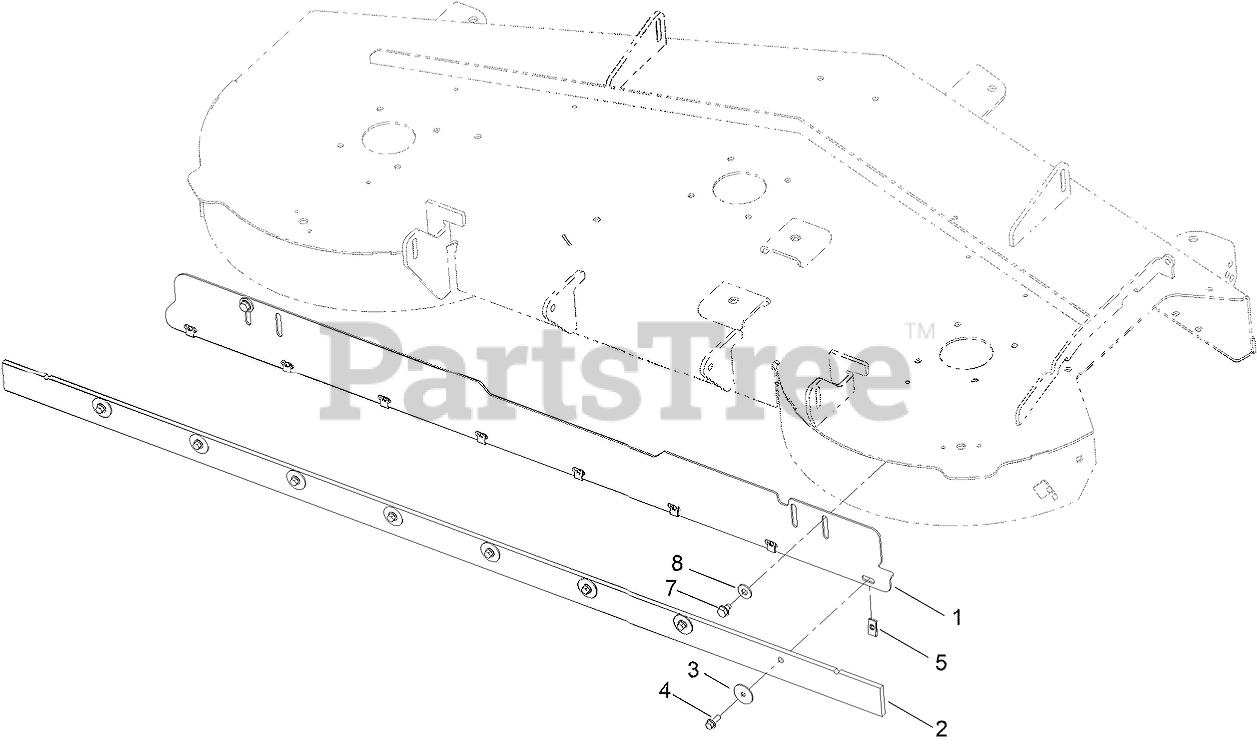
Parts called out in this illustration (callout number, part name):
3	WASHER-FLAT
4	SCREW-HHF
5	NUT-SPEED
7	SCREW-HWH, THD ROLL
8	WASHER-FLAT
